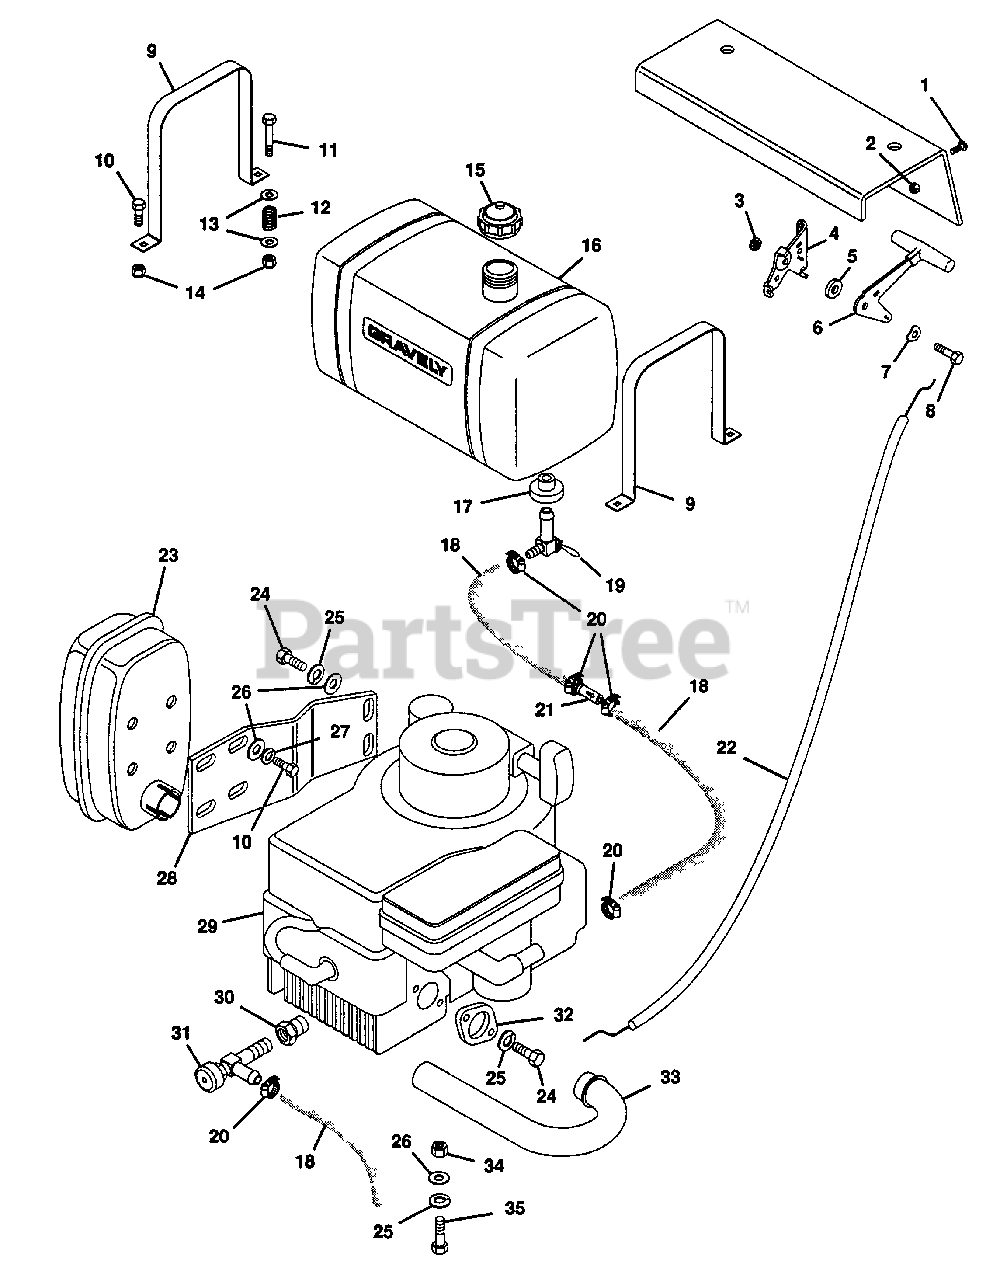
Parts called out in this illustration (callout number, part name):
1	SCREW, MACH. 10-32X.50 PHD
2	NUT, LOCK 10-32
3	NUT, LOCK 1/4-28
4	BRACKET, MOUNTING L.H.
5	WASHER, FRICTION
6	ASSEMBLY, KNOB AND LEVER
7	WASHER, SPRING
8	BOLT, HEX 1/4-28X.75
9	STRAP, FUEL TANK
10	BOLT, HEX 1/4-20X.75
11	BOLT, HEX 1/4-20X1.75
12	SPRING, COMP. 1X.78X338 LB/IN
13	WASHER, FLAT .406X.812X.065
14	NUT, LOCK 1/4-20
15	CAP, FUEL TANK
16	TANK, FUEL
17	BUSH., FLG. .375X1.06X.625 RB.
18	LINE, FUEL
19	VALVE, BALL SHUT-OFF
20	CLAMP, HOSE
22	ASSEMBLY, THROTTLE CONDUIT
23	MUFFLER
24	BOLT, HEX 5/16-18X.75
25	WASHER, LOCK 5/16 REG.
26	WASHER, FLAT .344X.688X.065
27	WASHER, LOCK 1/4 REG.
28	PLATE, EXHAUST
29	ENGINE, 12.5 HP B&S
30	ADAPTOR, OIL DRAIN
31	COCK, OIL DRAIN
32	FLANGE, MUFFLER
33	TUBE, EXHAUST
34	NUT, LOCK 5/16-18
35	BOLT HEX 5/16-18X1.75
